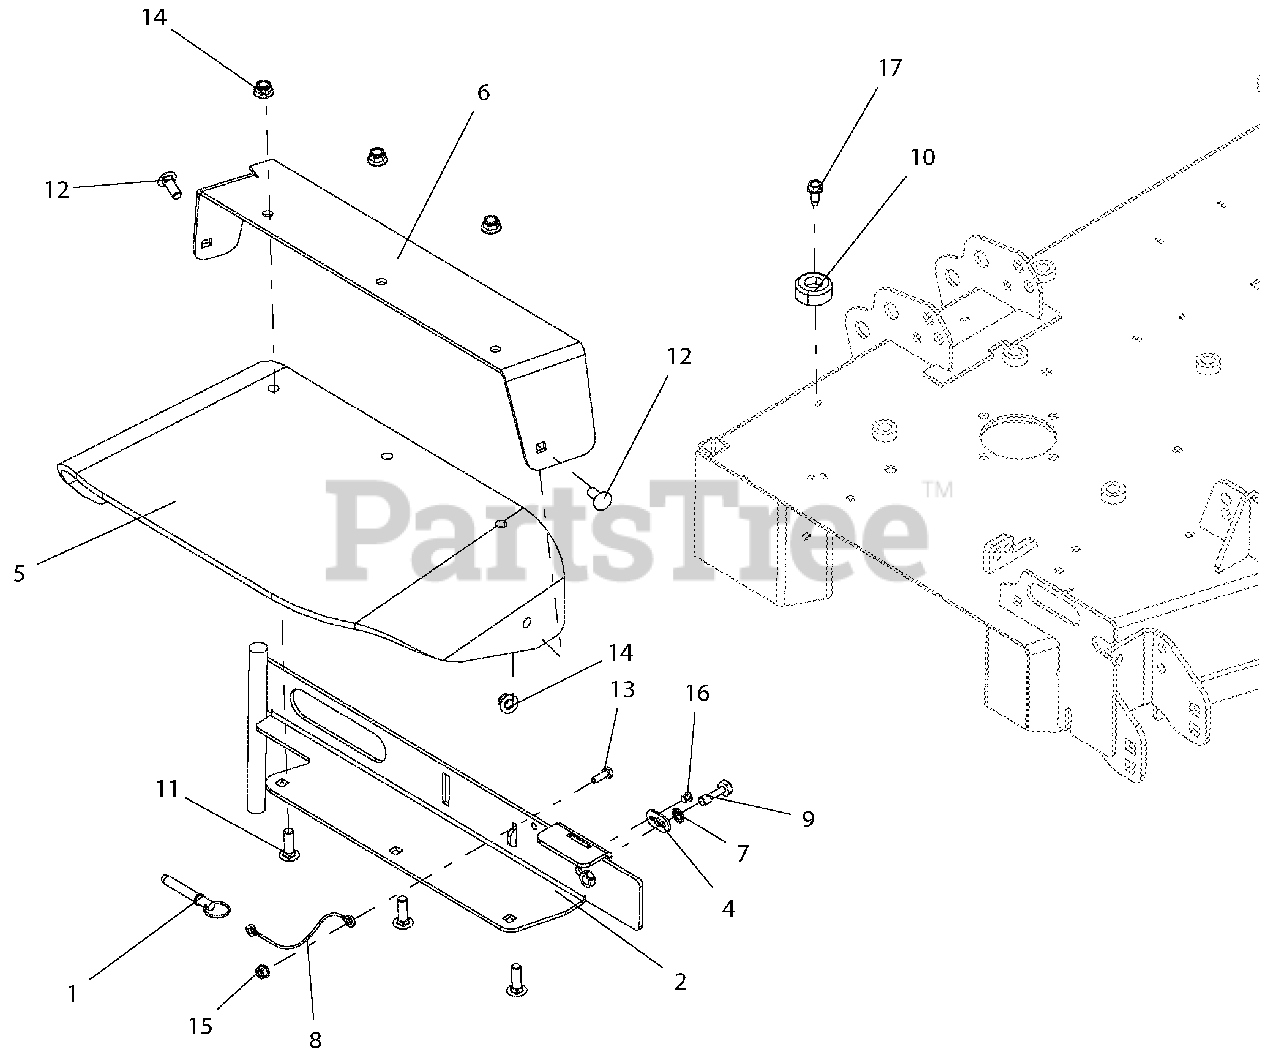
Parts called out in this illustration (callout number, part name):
1	PIN, SPRING BALL .375 OD X 1.50
2	WLDMT, 48" DISCHARGE CHUTE MTG-CE
4	KEEPER, BOLT
5	CHUTE, RUBBER DISCHARGE
6	KIT, PT DISCH CHUTE SUPT W/SAFETY DECALS-RED
7	LOCK, WSHR-EXT 0.391 X 0.628 X 0.036 YWZC
8	CABLE, 6.0 LANYARD, NYLON
9	BLT-HEX .38-16X1.25 GR5 CAP .37
10	BUMPER, RECESSED 1.50 X .63 W/.31 HOLE
11	BLT-RDHDSQNK .38-16X1.25 G5 YWZC
12	BLT-RDHDSQNK .38-16X1.00 G5 YWZC
13	BLT-HEX .25-20X.75 GR5 YWZC
14	NUT-LK-NYL-FLG .38-16 YWZC
15	NUT, LK-TOP-FLG .25-20 YWZC
16	RVT-POP .187x.250 (#64) YWZC
17	SCR-TAP .31-18X.75 HWH TR YWZ
